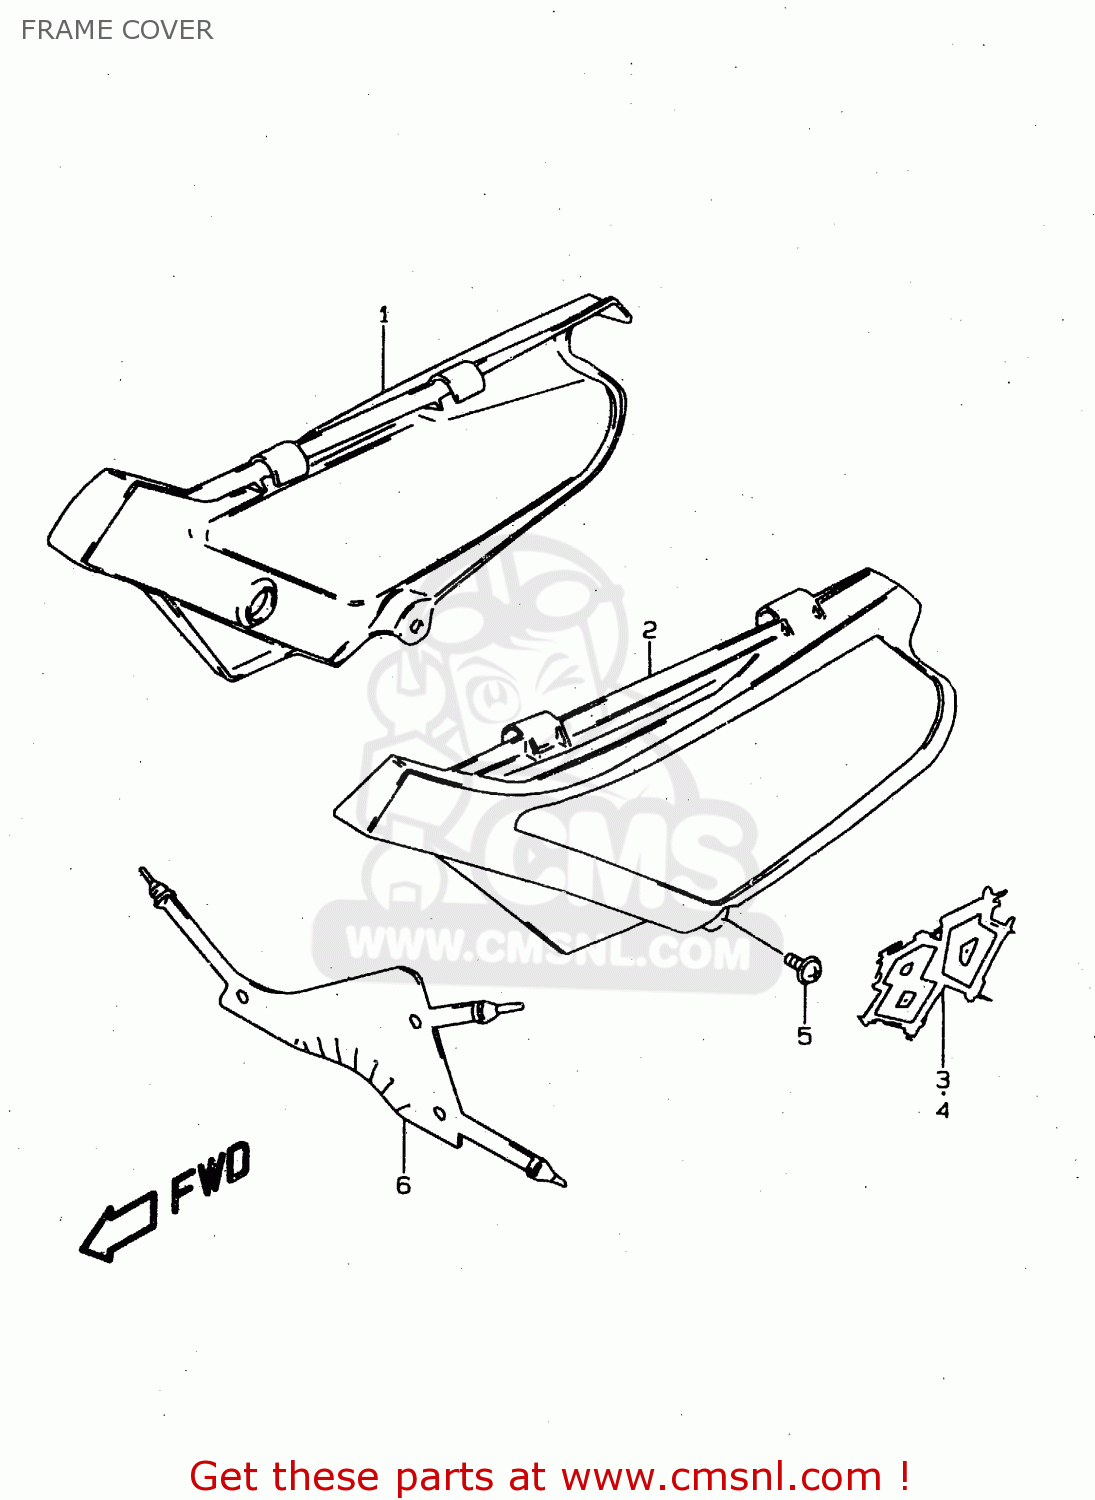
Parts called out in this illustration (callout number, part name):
1	COVER,FRAME,RIGHT
2	COVER,FRAME,L(WHITE)
3	EMBLEM,FRAME COVER
4	EMBLEM,FRAME COVER
5	SCREW(6X16)
6	MUD GUARD,FRAME COVER
